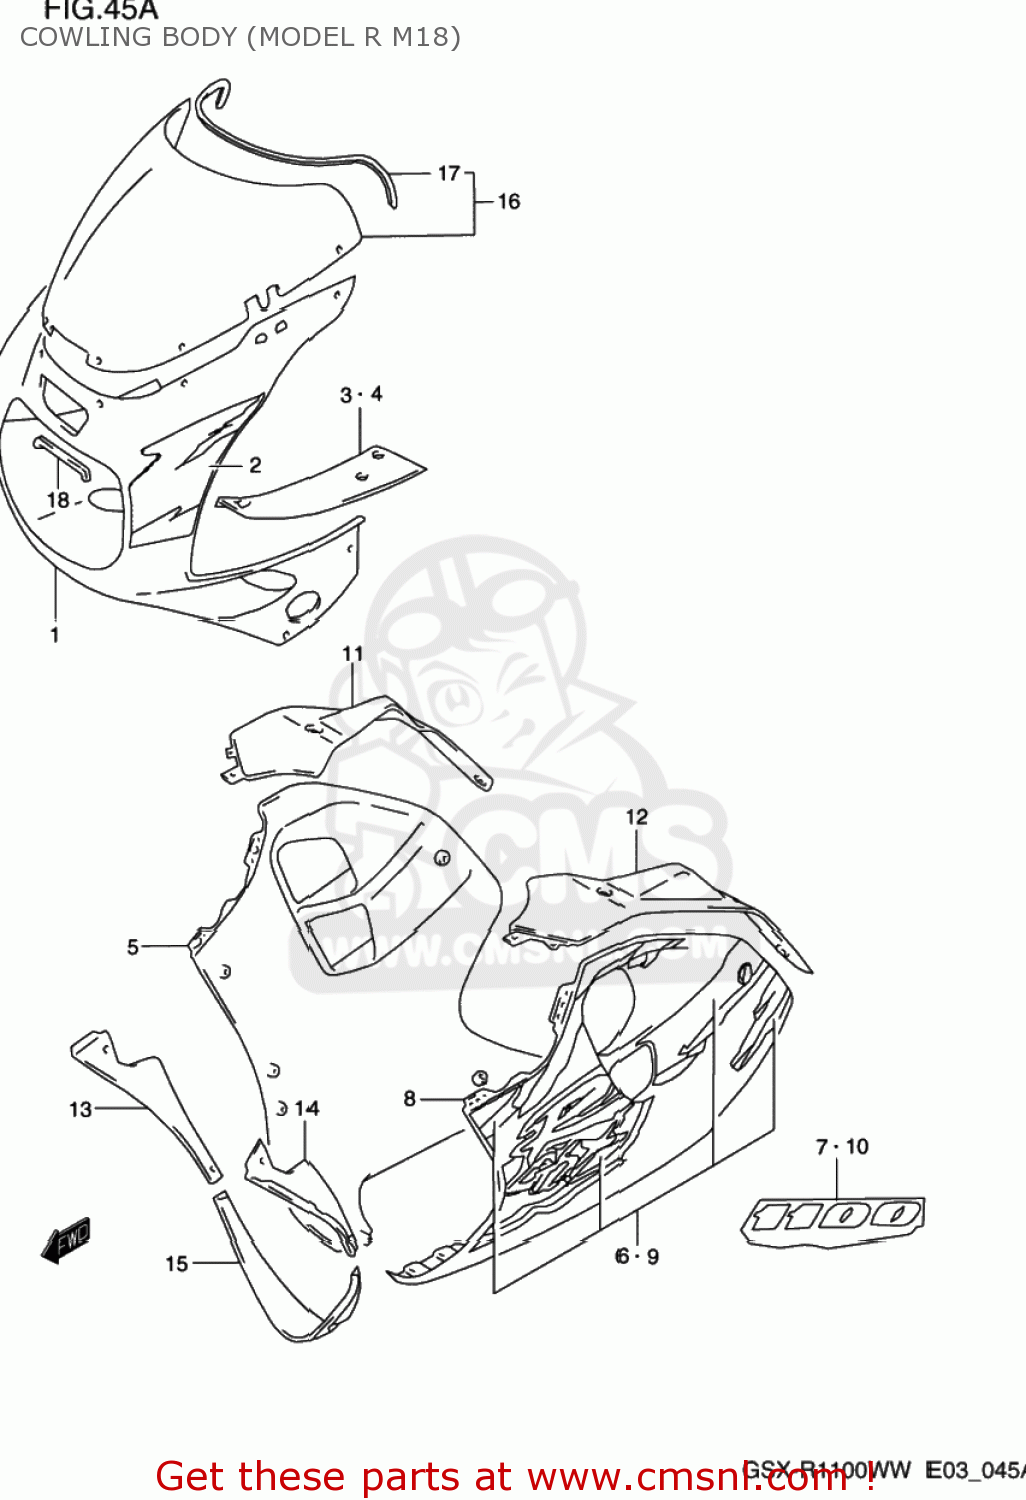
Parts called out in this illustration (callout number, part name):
1	COWLING ASSEMBLY,BODY
2	TAPE SET,COWL BODY
3	PANEL,UPR,R
4	PANEL,UPR,L
5	COWLING ASSEMBLY,UNDER,RIGHT
6	TAPE SET,COWLING,UNDER
7	EMBLEM,COWLING UNDER
8	COWLING ASSEMBLY,UNDER,LEFT
9	TAPE SET,COWL UNDER,L
10	EMBLEM,COWLING UNDER
11	PANEL,LWR,R
12	PANEL,LWR,L
13	COWLING,UNDER INNER,R
14	COWLING,UNDER INNER,L
15	COWLING,UNDER CTR
16	SCREEN SET,WIND
17	MOLDING,WINDSCREEN
18	CUSHION,FR POSITION LAMP
